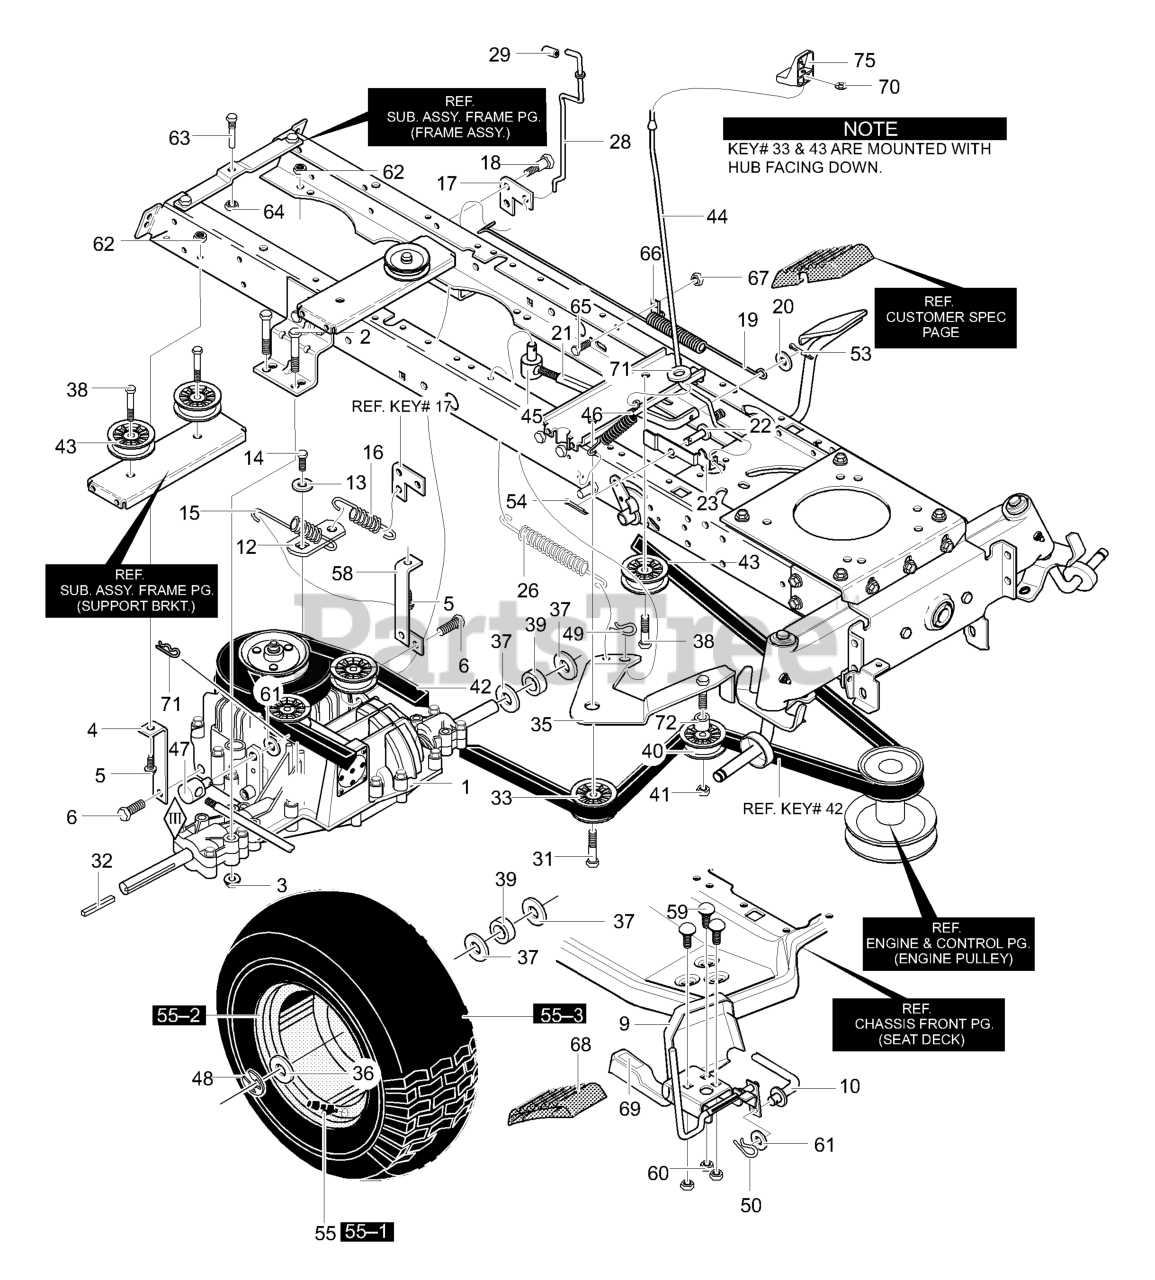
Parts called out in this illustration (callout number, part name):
1	Transaxle, VST205 **
2	SCREW, 5/16-18 x 2.50
3	NUT, 5/16-18
4	BRACKET, Stabilizer
5	SCREW, 5/16-18 x 1.00
6	SCREW, 5/16-18 x 0.75
9	Pedal Assy., Hydro
10	ROD, Foot Control
12	BRACKET, Shift
13	WASHER, Transaxle
14	SCREW, 1/4-28x.75
15	SPRING - Transaxle
17	Disconnect Bracket
18	BOLT, HHSH 5/16-18
19	SPRING, Brake
20	WASHER, Flat
21	ROD, Clutch
22	PIN, Clevis
23	Latch, Park Brake
26	SPRING, Tension
28	ROD, Disconnect Ctrl
29	GRIP, Hydro Disconnect
31	SCREW, 3/8-16 x 1.25
32	Key, Square
33	PULLEY, Idler
35	ASSEMBLY, Idler Arm Traction
36	WASHER, Flat
37	WASHER, Flat
38	SCREW, 3/8-16 x 1.25
40	PULLEY, Idler
41	NUT, 3/8-16
42	BELT, V 4L 112.75
43	PULLEY, Idler
44	ROD-Parking Brake
45	NUT, 5/16-18 Adjusting
46	Extension Spring
47	Adjusting Nut 1/2-13
49	PIN, Hair
50	PIN, Hair
53	PIN, Cotter
54	PIN, Cotter
55	Tire & Rim
55-1	Valve Stem
58	BRACKET, Stabilizer
59	BOLT, Carr. 5/16-18x.75
60	NUT, 5/16-18
61	FLATWASHER
62	NUT, 1/4-20
63	SCREW Guide
64	NUT, 5/16-18
65	SCREW, 1/4-20x.50
66	Retainer, Wire
67	NUT, 1/4-20
68	Pad, Speed Ctrl Pedal
69	Pad, Toe Sandpaper
70	Pushnut
71	WASHER, Flat
72	SPACER 1/2 to 17MM
75	Parking Brake Knob
